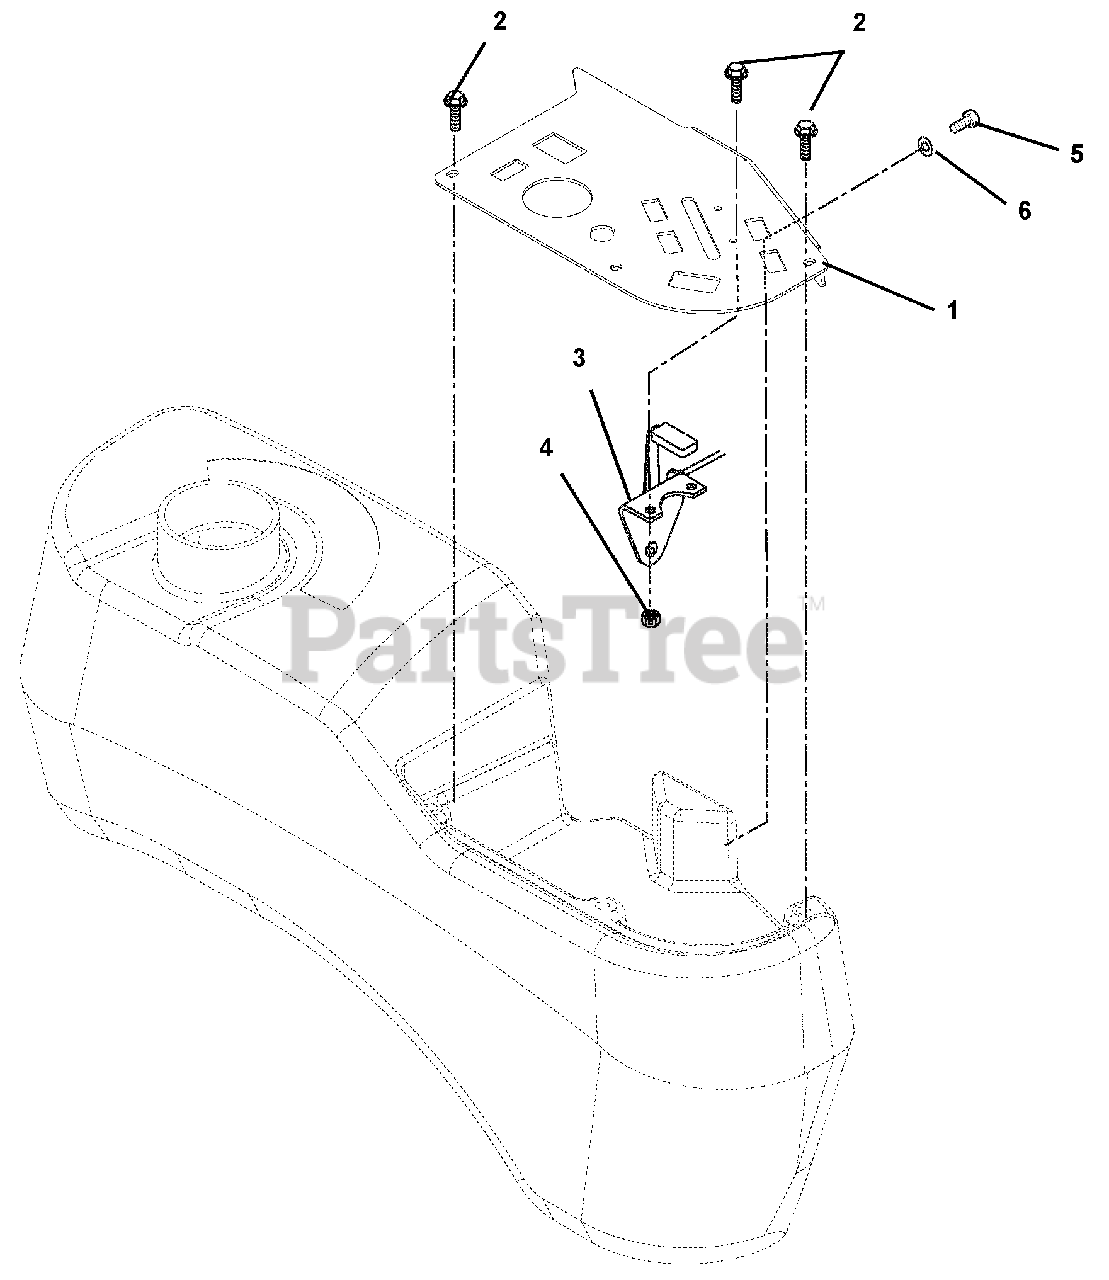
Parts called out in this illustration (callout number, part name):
1	PANEL, CONTROL MZ DIESEL BLACK
2	SCR-MCH 10-24X.50 HWHSTAINLESS
3	CABLE, THROTTLE-DIESEL
4	@NUT-LK-NYL 10-24 W/INSRT YWZC
5	@BLT-HEX .31-18X.75 GR5 YWZC
6	@WSHR-FL-STL.38X.875X.083 YWZC
